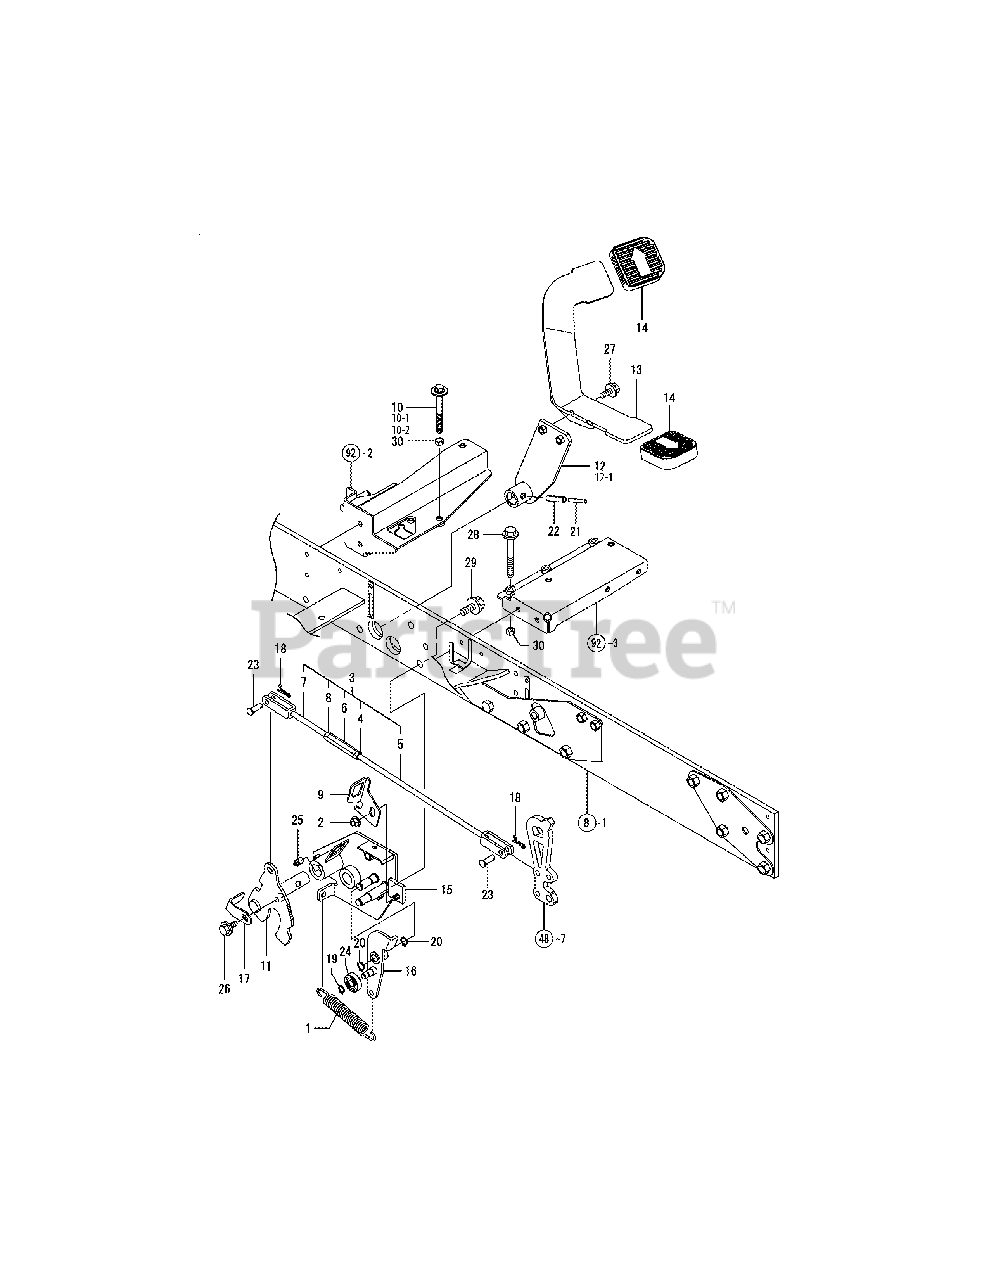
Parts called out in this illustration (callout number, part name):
1	SPRING, RETURN
2	NUT W/WASHER 8
4	NUT W/WASHER 8
5	ROD B CMP, HST
6	TURNBUCKLE 8X60
10	BOLT, HST PEDAL
10-1	BOLT, HST PEDAL
10-2	BOLT, M8 X 85 PLATED
12	PEDAL, ARM CMP
12-1	PEDAL, ARM CMP
13	PEDAL , HST CMP
15	FULCRUM, PEDAL CMP
16	ARM, SWITCH CMP
18	PIN 8, COME-OFF SNAP
21	SPRING PIN 5X40
22	SPRING PIN 8X40
25	NIPPLE PT1/8, GREASE
26	BOLT M 8X 16 PLATED
27	BOLT M 8X 20 PLATED
28	BOLT M 8X 80 PLATED
29	BOLT M10X 25 PLATED
